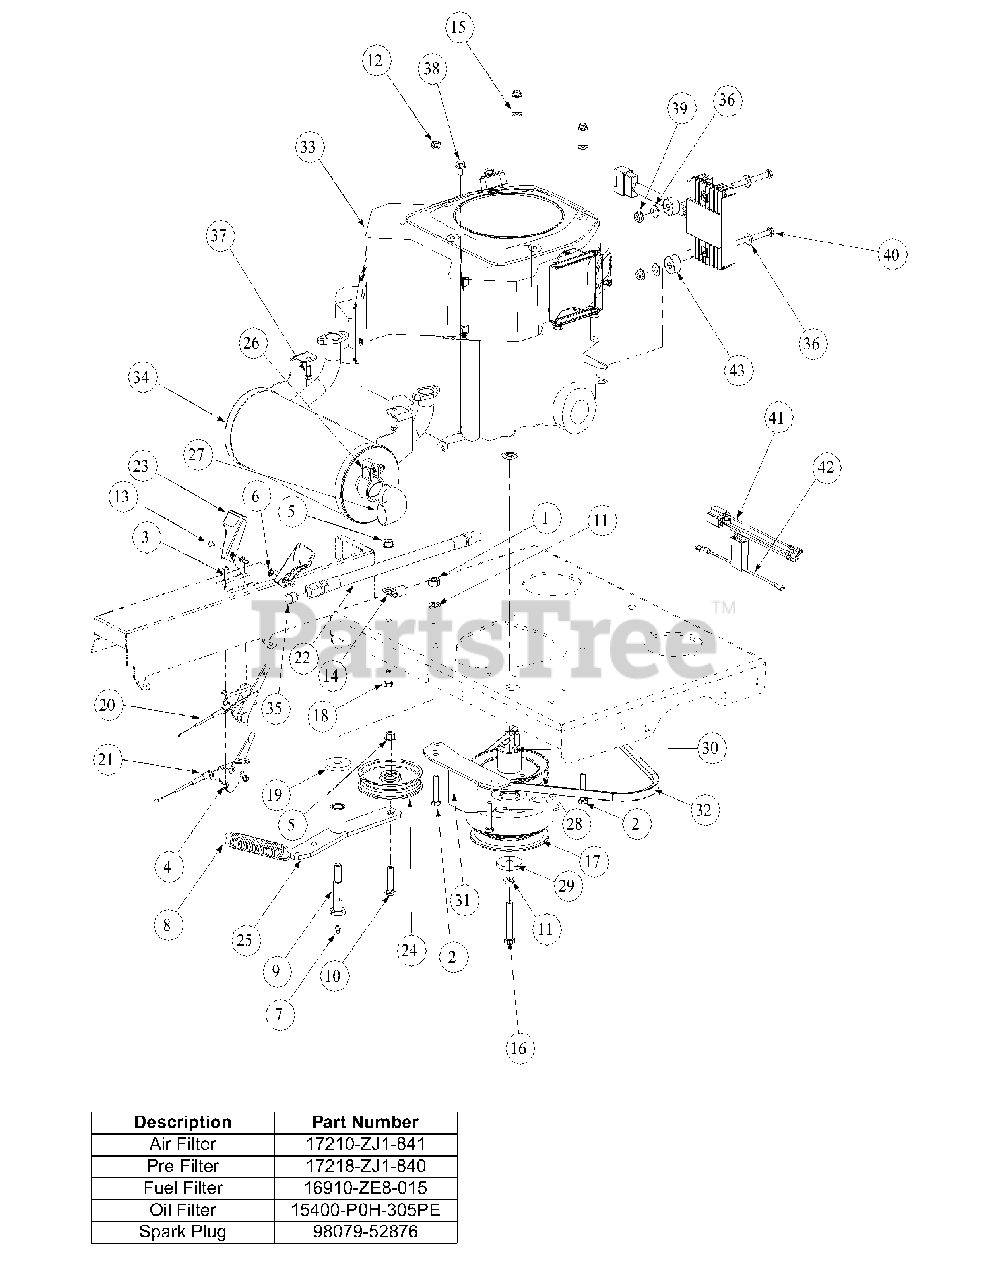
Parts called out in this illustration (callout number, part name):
1	Hex Nut, 7/16-14
2	HHCS, 5/16-18, 1-3/4
3	Round Hd. Machine Screw, 10-32 x 3/4
4	Lock Nut, Nylon Insert, 10-32
5	Flange Lock, Hex Nut, 3/8-16
6	Nut Washer, W/Star, 8-32
7	Grease Fitting, 1/4-28 x 3/16
8	Extension Spring, 1.0 OD x 5.125
9	Shoulder Screw, 7/16-14
10	Hex Carriage Screw, 3/8-16, 1.75
11	Lock Washer, 7/16
12	Hexflange Lock Nut, 5/16-18
13	Machine Screw, 8-32, .375
14	Clip, Heat Shield Cable
15	Flat Washer, 5/16
16	Capscrew, 7/16-20 x 3.50
17	Clutch Electric, Ogura JD08
18	Hex Cap Screw, 3/8-16, .750
19	Flat Washer, 7/16 ID x 1.75 OD x .25
20	Choke Control Cable
21	Throttle Control Cable
22	Oil Drain Hose
23	Control Throttle Knob
24	Flat Pulley with Flanges
25	Engine Idler Arm Assembly includes:
25	Bearing
26	Tube Clamp, 1.50
27	Muffler Accessory Exhaust Tube
28	Trans Drive Pulley
29	Flat Washer, 7/16 ID x 1.75 OD x .25
30	Key, 1/4 x 1/4 x 2.75
31	Retainer Clutch Assembly, Ogura
32	Belt, 51.2 Lg
33	Engine, 20HP Honda, use Engine Oil 10W40
34	Muffler
35	Pipe Plug, 3/8 NPT
36	Flat Washer, 1/4
37	Hex Cap Screw, M8-1.25 x 18mm
38	Screw, M6 x 1.0 x 12mm
39	Nut, 1/4-20, Hex Flange Lock
40	Hex Cap Screw, 1/4-20 x 2.50
41	Wire Harness Adapter
42	Charge Regulator Wire
43	Spacer, .281 ID x .875 OD
